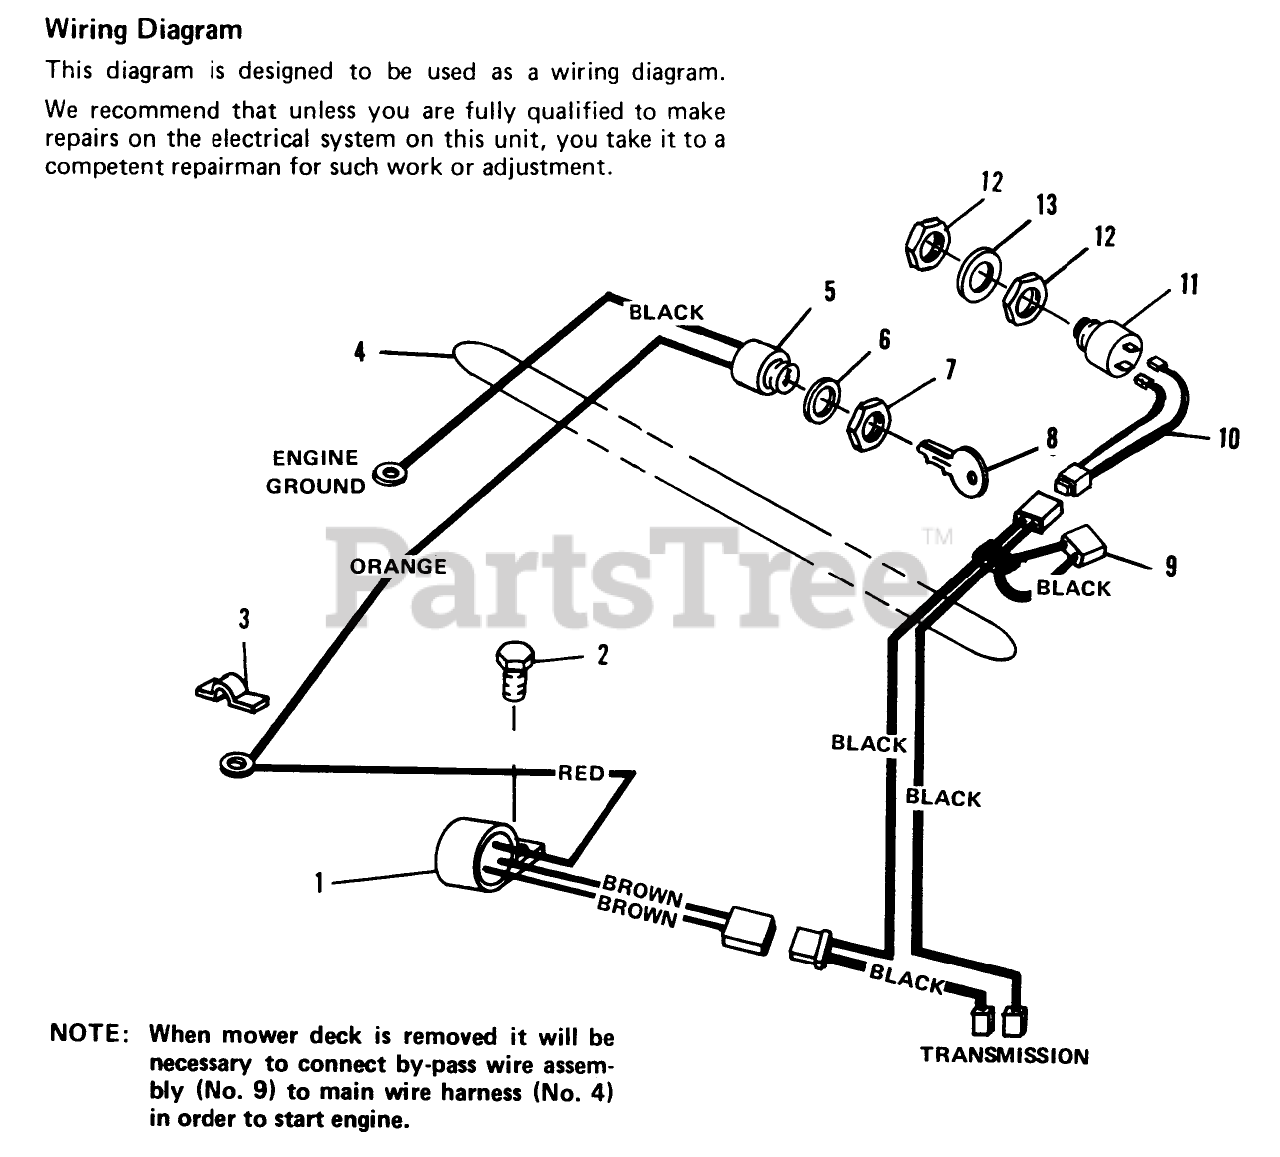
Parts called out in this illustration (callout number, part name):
1	Cup-Starter
2	Screw, No.10-32 x 1/2 In.
3	Press Clip
4	Wire Harness
5	Switch, Ignition
6	WASHER-LOCK
7	Nut (Ignition Switch Part)
8	Key, Ignition
9	Wire Assembly, By-Pass
10	Wire Assembly, Deck Switch
11	Switch, Lockout
12	Nut (Switch Part)
13	Lockwasher (Switch Part)
72	Tag, Warranty (Not Illustr.)
